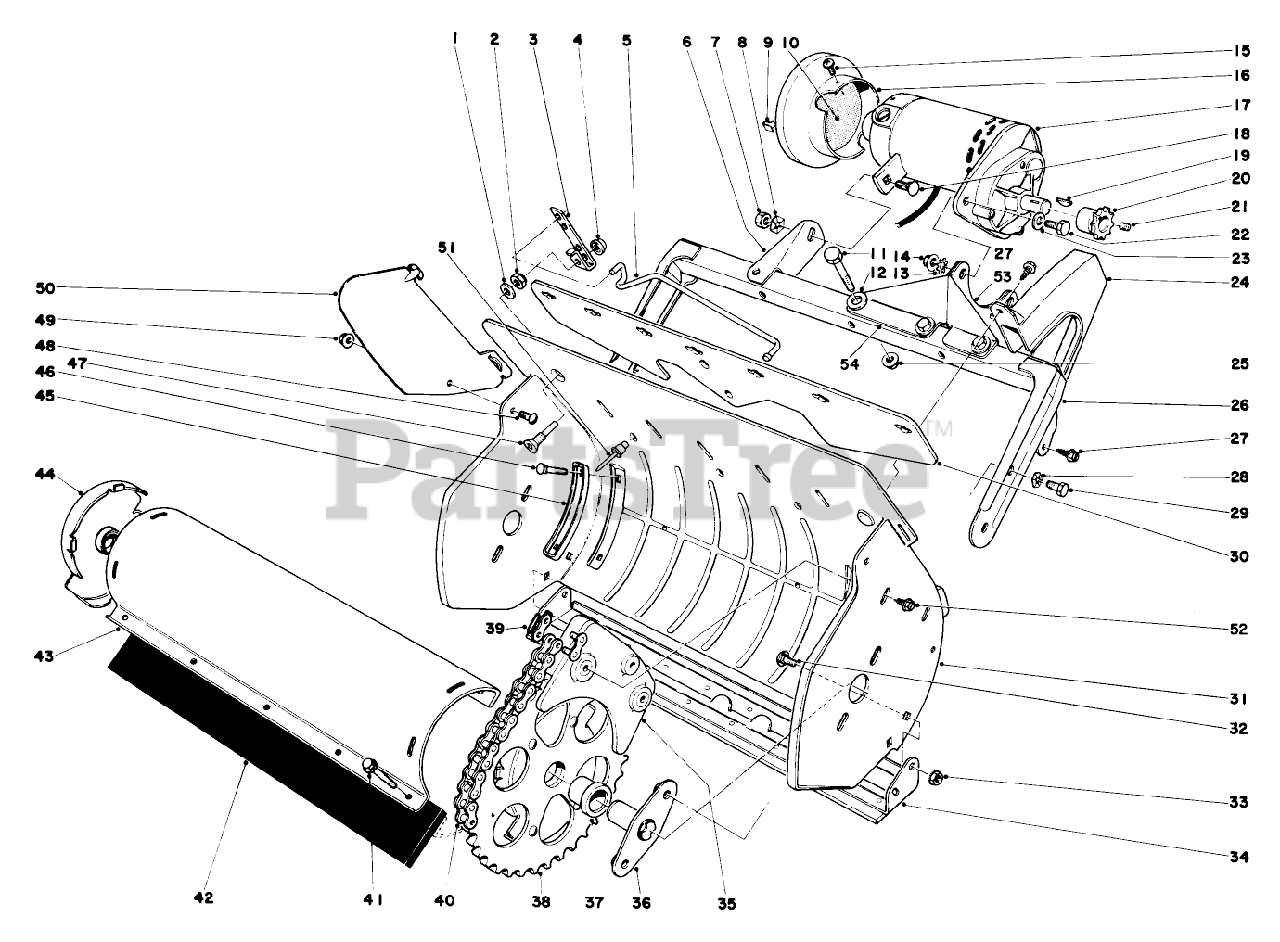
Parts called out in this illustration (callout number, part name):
1	WASHER-FLAT
2	NUT-LOCK, NI
6	Bracket Rear
7	NUT-HEX
8	WASHER-LOCK
9	Clip Tinnerman
10	Filter Assy.
11	SCREW-HH
12	WASHER-FLAT
14	NUT-HHF
16	Housing
17	Motor
18	BOLT-CARR
21	SCREW-SET, HSH
22	SCREW-HH
23	WASHER-PLAIN
26	Frame
27	SCREW-HWHTF
31	Housing
33	NUT-KEPS
39	LINK-CONNECTING, NO. 35
40	CHAIN
42	ROTOR BLADE
46	SCREW-CARR
48	SCREW-PTH
49	NUT-LOCK, FLANGE
53	Bracket Motor
54	Bracket Motor
